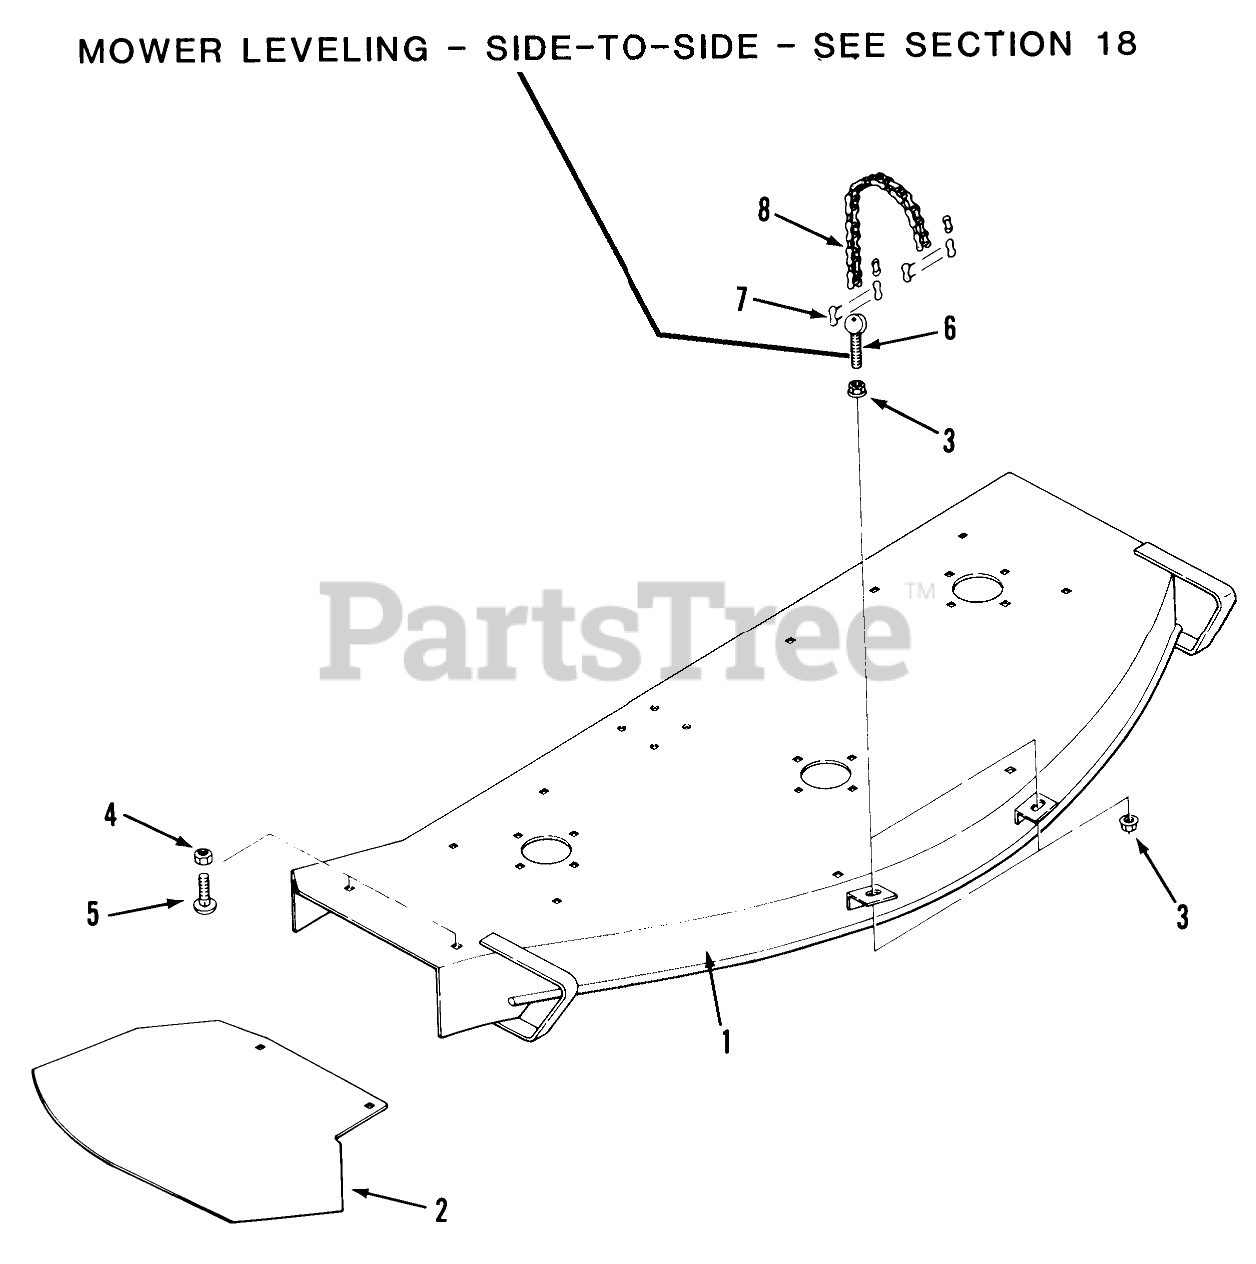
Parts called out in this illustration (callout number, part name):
1	Mower Deck
2	Discharge Chute
3	NUT
4	Nut
5	Bolt
6	Eye Bolt 3/8-16 2 1/8
7	MASTER LINK CHAIN
8	Mower Deck Lift Chain
